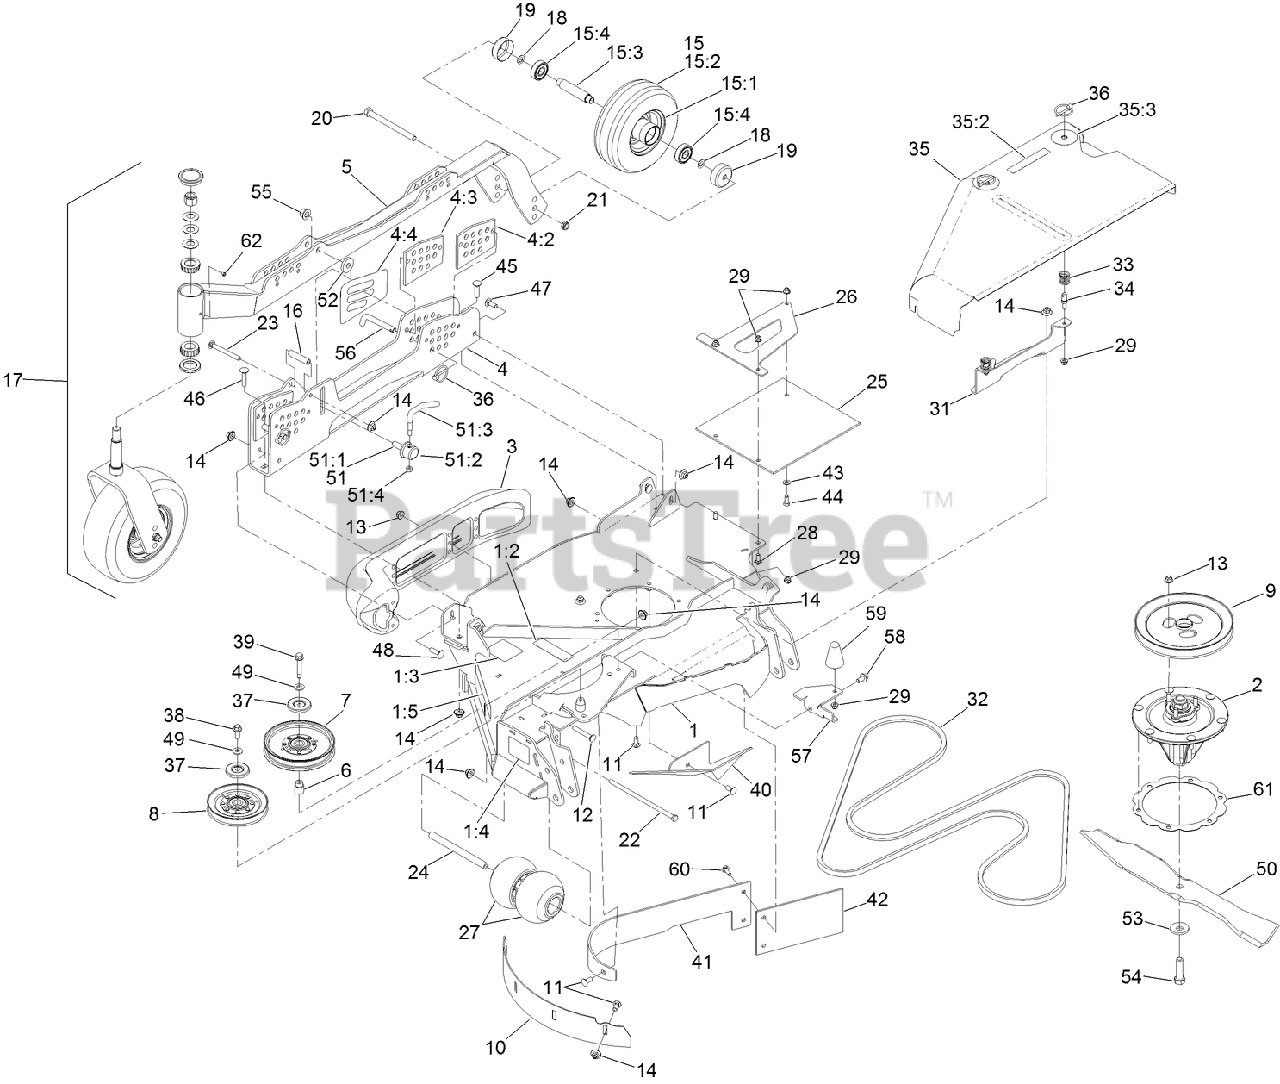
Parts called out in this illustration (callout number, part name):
1	RH WING DECK DECAL ASM
1:2	DECAL-COVER, MISSING
1:3	DECAL-DANGER, THROWN OBJECT
1:4	DECAL-WARNING, PINCH POINT
2	SPINDLE ASM
3	SKID-BUMPER, DECK
4	RH HOC CHANNEL ASM
4:2	PLATE-GUIDE, HOC (LH)
4:3	PLATE-GUIDE, HOC (RH)
4:4	DECAL-HEIGHT OF CUT, RH
6	BUSHING-IDLER
7	IDLER-PULLEY
8	IDLER-V
9	SHEAVE-SINGLE 96 RD (TORO)
10	BAFFLE-DEPTH, RH
11	BOLT-CARR
12	SCREW-CARR
13	NUT-HF, NI
14	NUT-FLANGE, NI
15	WHEEL AND TIRE ASM
15:1	WHEEL
15:3	AXLE-CASTER
15:4	BEARING
16	SPACER
17	CASTER WHEEL ASM
18	WASHER-PLAIN
19	GUARD-SEAL
20	SCREW-HH
21	NUT-HEX
22	SCREW-HH
23	SCREW-CARR
24	SPACER-WHEEL
25	GUARD-TIRE
26	SUPPORT-FLAP, RH
27	ROLLER-SCALP, ANTI
28	SCREW-CARR
29	NUT-HF, NI
31	BRACKET-SHIELD MOUNT, OUTER
32	BELT-V
33	SPRING
34	PIN-SPRING
35	RH WING SHIELD ASM
35:2	DECAL-NO STEP
35:3	DECAL-SCRATCH COVER
36	PIN-LYNCH
37	SHIELD-DUST
38	SCREW-HHF
39	SCREW-HHF W/ PATCH
40	BAFFLE-DEFLECT, RH
41	BAFFLE-DOGLEG, RH
42	FLAP-RUBBER
43	WASHER-PLAIN
44	SCREW-HH
45	SCREW-HH
46	SCREW-HH
47	SCREW-HH
48	BOLT-CARR
49	WASHER-BELLEVILLE
50	BLADE-MULCH, 24.5IN
51	LEVER ASM
51:1	SCREW-LOCK
51:2	CAP-LOCK
51:4	NUT-LOCK, NI
52	WASHER
53	WASHER-BLADE BOLT, HEAVY
54	SCREW-BLADE
55	NUT-LOCK
56	PIN-HOC
57	BRACKET-COVER RETAINER
58	SCREW-HWH
59	BUMPER-RUBBER
60	SCREW-CARR
61	RING-SPACER, HOUSING
